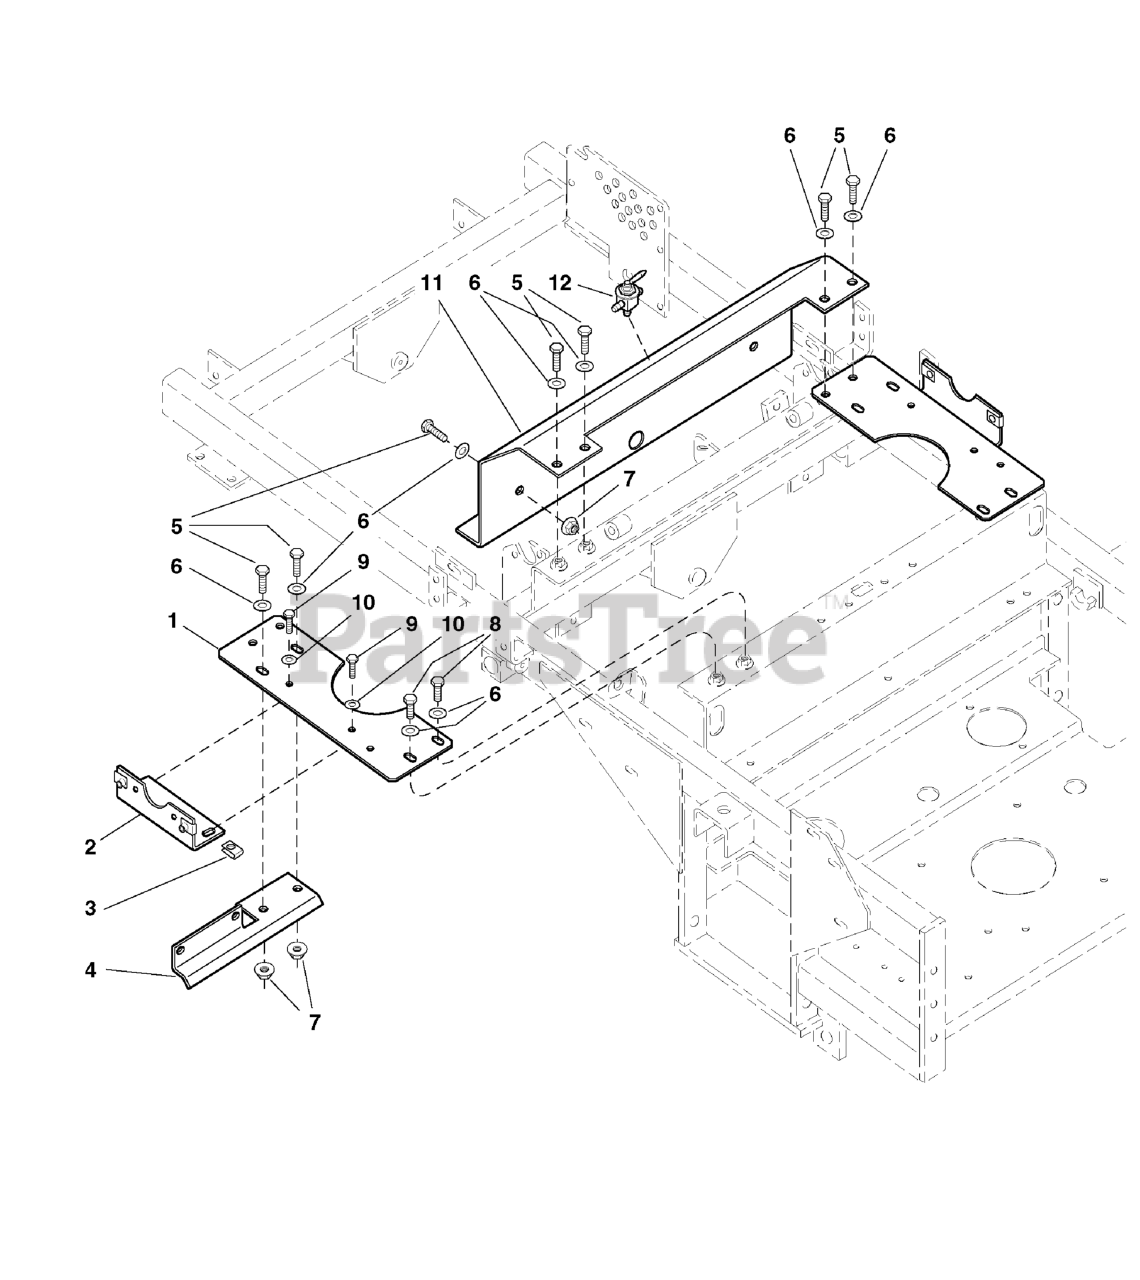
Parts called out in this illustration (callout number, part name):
1	COVER MOUNT PLATE
2	BRACKET, Cover Mount
3	BODY CLIP, 5/16-18-7GA MATERIAL
4	INSTRUMENT PANEL MOUNT
5	BOLT, 3/8-16 X 1" GD5 CZ
6	WASHER, 3/8 SAE
7	NUT, 3/8-16 Hex Serrated Flange
8	BOLT, 3/8-16 X 3/4" GD5 CZ
9	BOLT, 5/16-18 X 1 GD5 YZ
10	WASHER, 5/16" SAE
11	BRAKE COVER PANEL
12	VALVE, Fuel Shut Off
